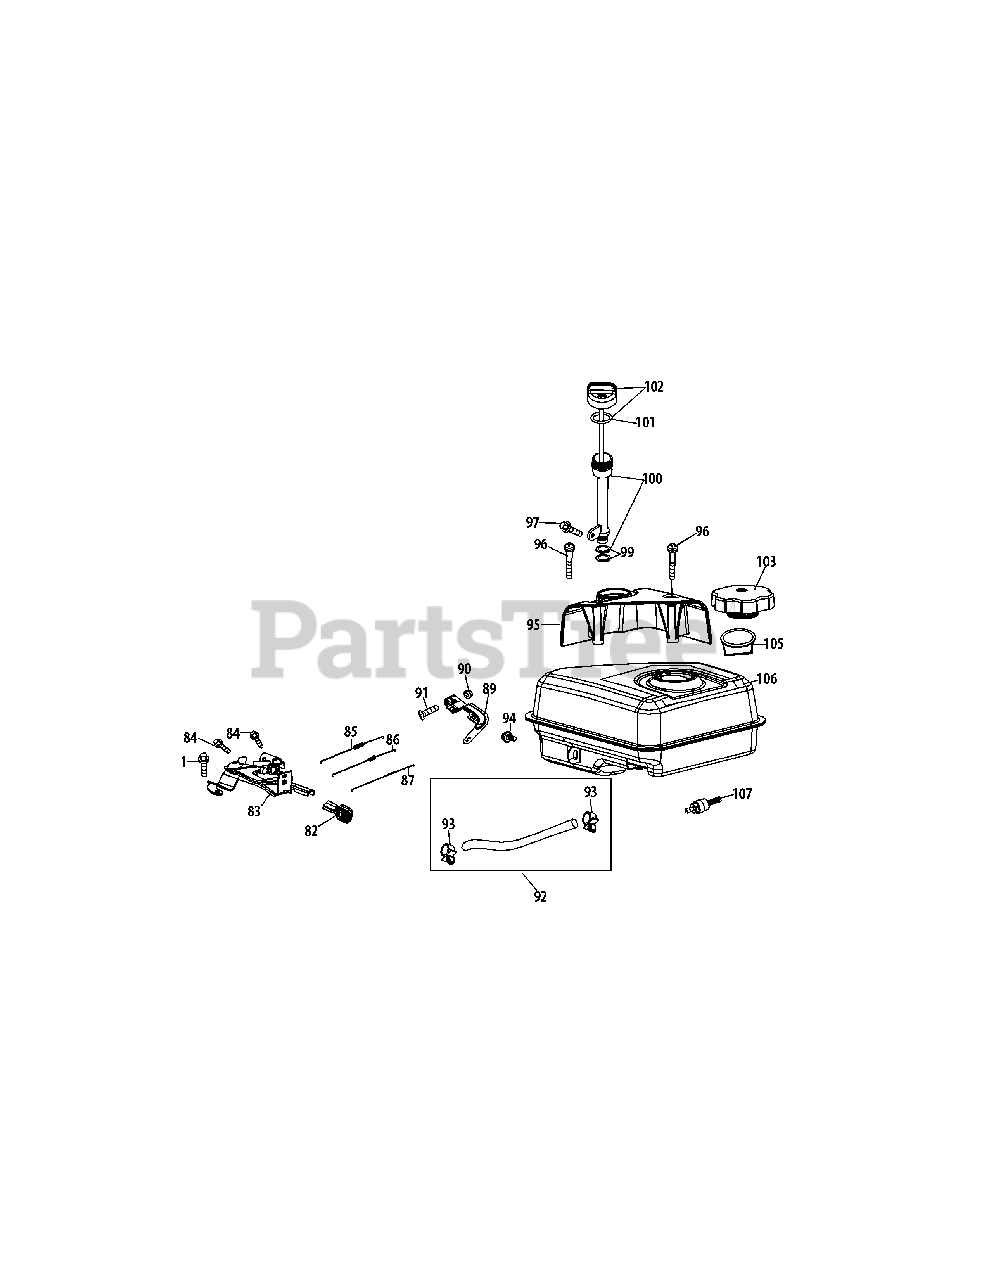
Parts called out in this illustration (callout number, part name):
1	Bolt M6×16
82	Throttle Control Knob
83	Primer Bracket
84	Bolt M6×12
85	Governor Spring
86	Throttle Linkage Spring
87	Throttle Linkage
89	Governor Arm
90	Nut M6
91	Governor Arm Bolt
92	Fuel Line Kit
93	Fuel Hose Clamp
94	Bolt M6×12
95	Dipstick Decoration Cover
97	Bolt M6×12
99	Oil Fill Tube O-Ring
100	1/ 4 Turn Oil Fill Tube
101	Dipstick O-Ring
102	Dipstick Guage
103	Fuel Cap Assembly
105	Fuel Level Indicator
107	Fuel Tank Nipple
